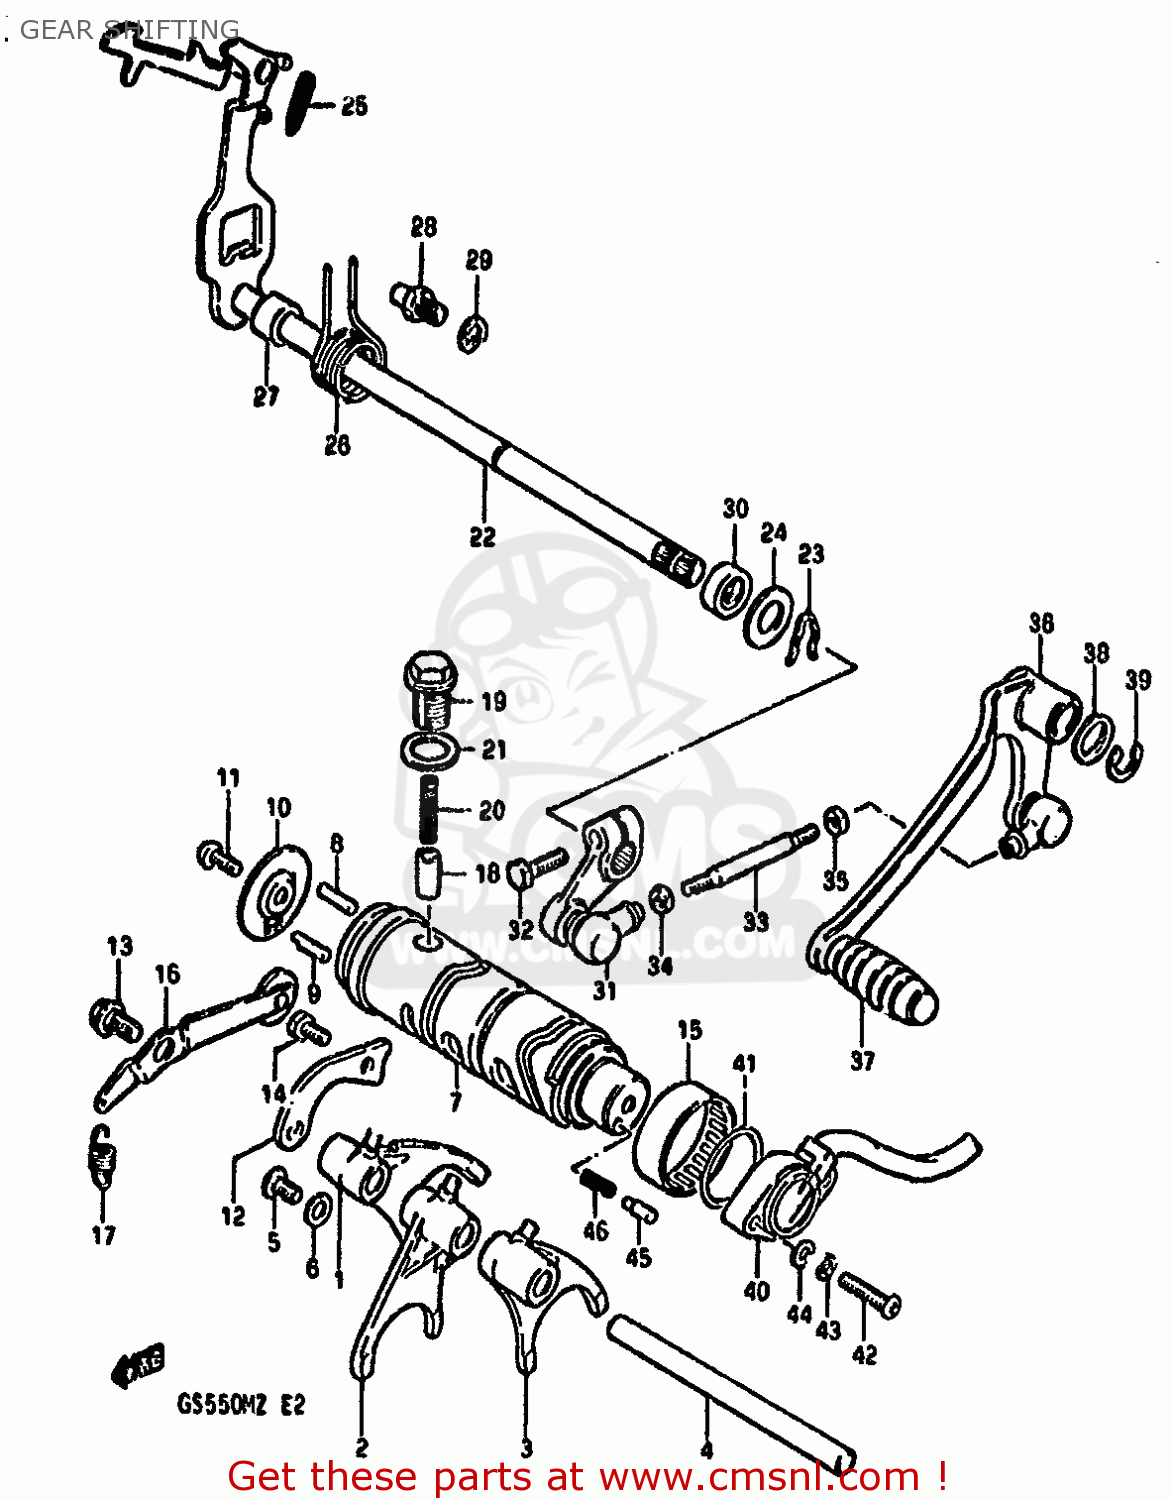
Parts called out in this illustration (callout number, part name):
1	FORK,GEAR SHIFT NO.1
2	FORK,GEAR SHIFT NO.2
3	FORK,GEAR SHIFT NO.2
4	SHAFT,GEAR SHIFT FORK
5	SCREW
6	WASHER
7	CAM,GEAR SHIFT
8	PIN(4X18.5)
9	PIN
10	RETAINER,GEAR SHIFT CAM DR PIN
11	SCREW
12	GUIDE,GEAR SHIFTING CABLE
13	BOLT
14	BOLT
15	BEARING(40X47X12)
16	STOPPER,GEAR SHIFT CAM NO.1
17	SPRING
18	STOPPER,GEAR SHIFT CAM NO.2
19	HOLDER,GEAR SHIFT CAM STOP SPR
20	SPRING
21	GASKET(14X19.2X2) (NAS)
22	SHAFT,GEAR SHIFT
23	SPRING,RETAINER
24	WASHER (12.5X27X1.6)
25	SPRING
26	SPRING
27	SPACER(12X20X15.3)
28	STOPPER,GEAR SHIFT CAM
29	WASHER
30	OIL SEAL
31	ARM,GEAR SHIFT LINK
32	BOLT
33	ROD,GEAR SHIFT LINK
34	NUT
35	NUT
36	LEVER ASSY,GEAR SHIFTING
37	RUBBER,GEAR SHIFT PEDAL
38	WASHER(12.5X20X1)
39	CIRCLIP
40	TERMINAL BASE ASSY,GEAR SHIFT
41	O-RING (D:2.4 ID:26.2)
42	SCREW 5X20
43	LOCK WASHER
44	WASHER
45	PIN(5X15.5)
46	SPRING
